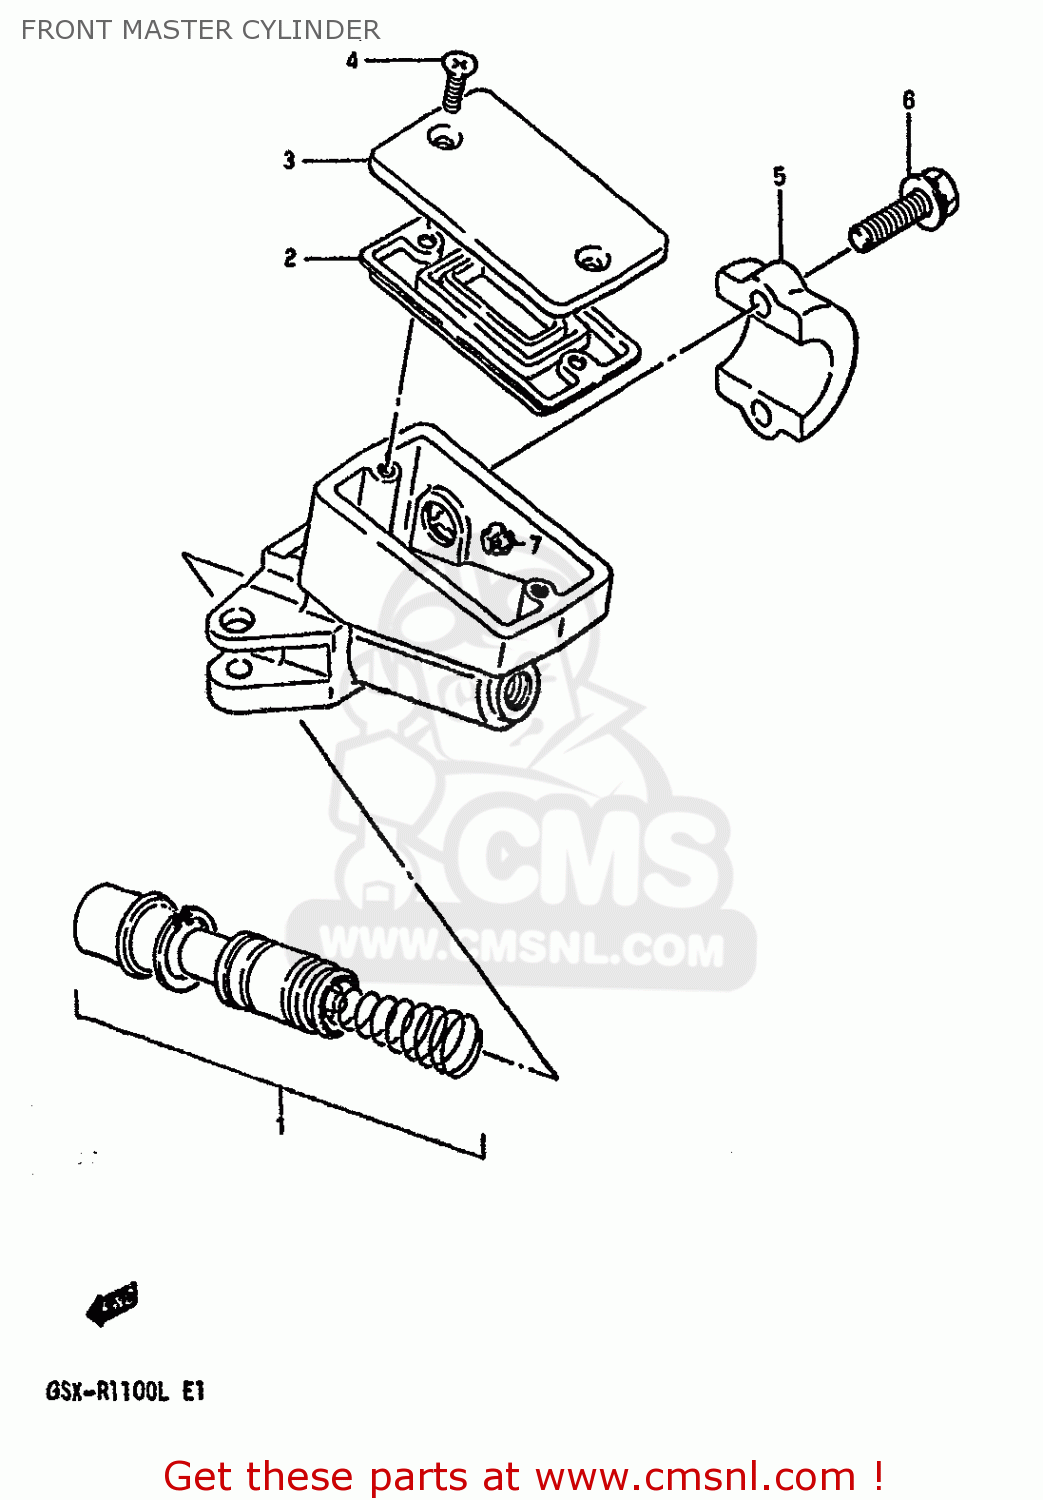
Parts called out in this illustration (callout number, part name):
1	PISTON & CUP SET
2	3-1
3	CAP
4	SCREW
5	HOLDER
6	BOLT
7	PROTECTOR
